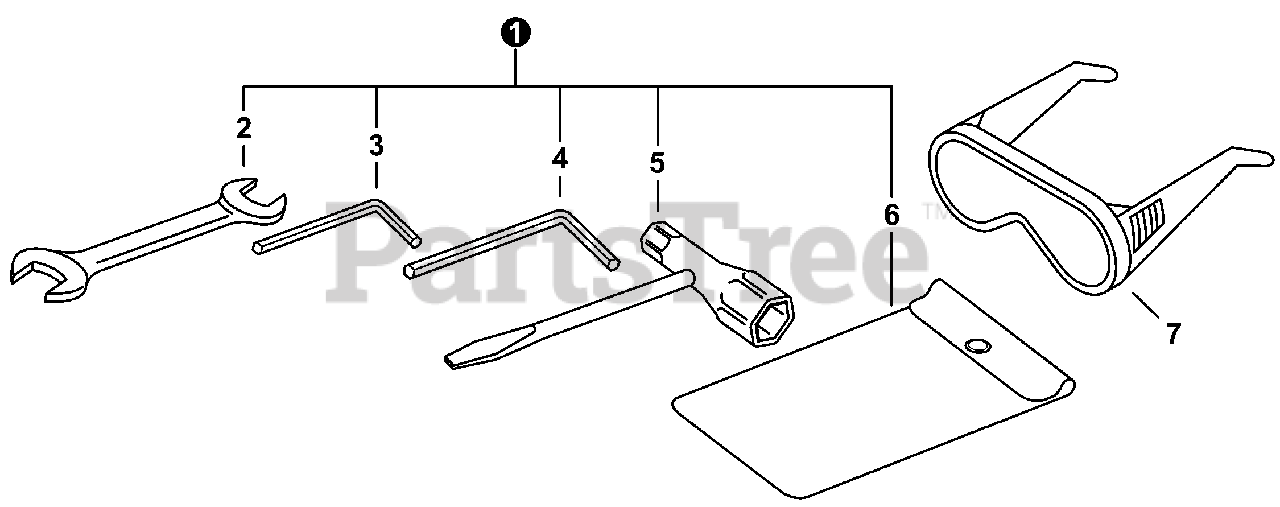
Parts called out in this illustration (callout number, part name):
1	TOOL KIT, SERVICE
2	SPANNER 8x10
3	WRENCH, ALLEN 4 MM
4	WRENCH, ALLEN 5 MM
5	T-WRENCH 17x19 MM
6	BAG, TOOL
7	GLASSES, SAFETY
